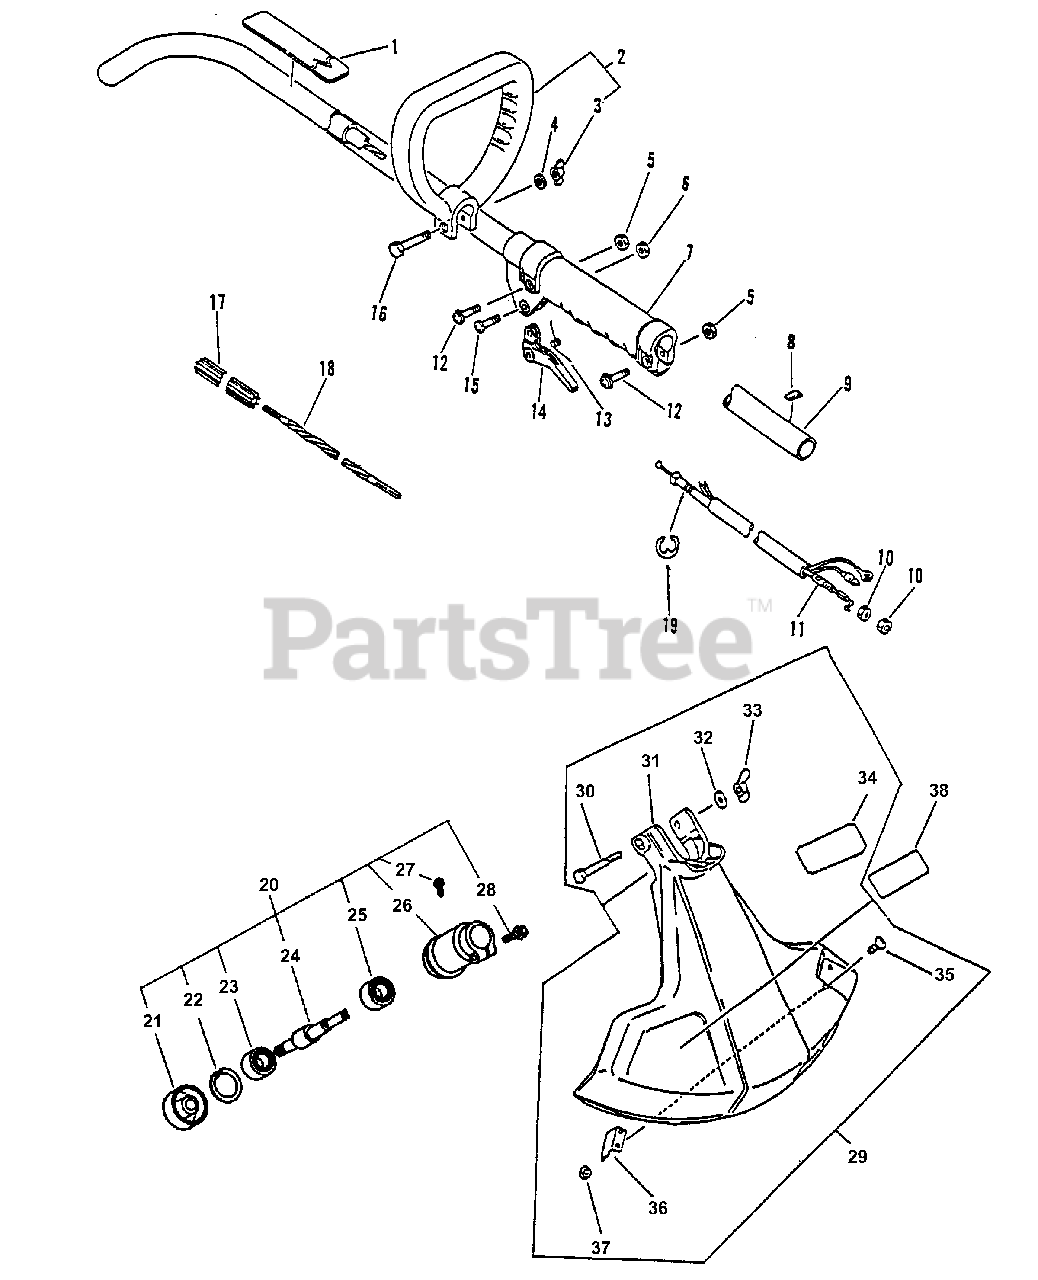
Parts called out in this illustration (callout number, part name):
1	LABEL, CAUTION
2	HANDLE ASSY
3	NUT - 1/4-20
4	WASHER, 1/4"
5	NUT M5
6	NUT, LOCK M5
8	LABEL - ALIGNMENT
9	MAIN PIPE ASSY
11	CABLE, THROTTLE
12	SCREW 5×25
13	SPRING, THROTTLE
14	TRIGGER, THROTTLE
16	BOLT 1/4"-20×1-1/2"
17	LINER - FLEXIBLE
18	DRIVESHAFT - FLEXIBLE
19	E-RING 4
20	GEAR CASE ASSY
21	PLATE, ADAPTER - UPPER
22	E-RING 30
23	BEARING, BALL 6200
24	GEAR, SHAFT
25	BEARING, BALL 6200
26	CASE, GEAR
27	SCREW 4×10
28	BOLT - 5×25
29	DEBRIS SHIELD KIT
30	BOLT 1/4"-20×2"
31	SHIELD
32	WASHER, 1/4"
33	NUT - 1/4-20
34	LABEL, CAUTION
35	SCREW 5×16
36	CUTTER, LINE
37	NUT M5
38	LABEL, ECHO
